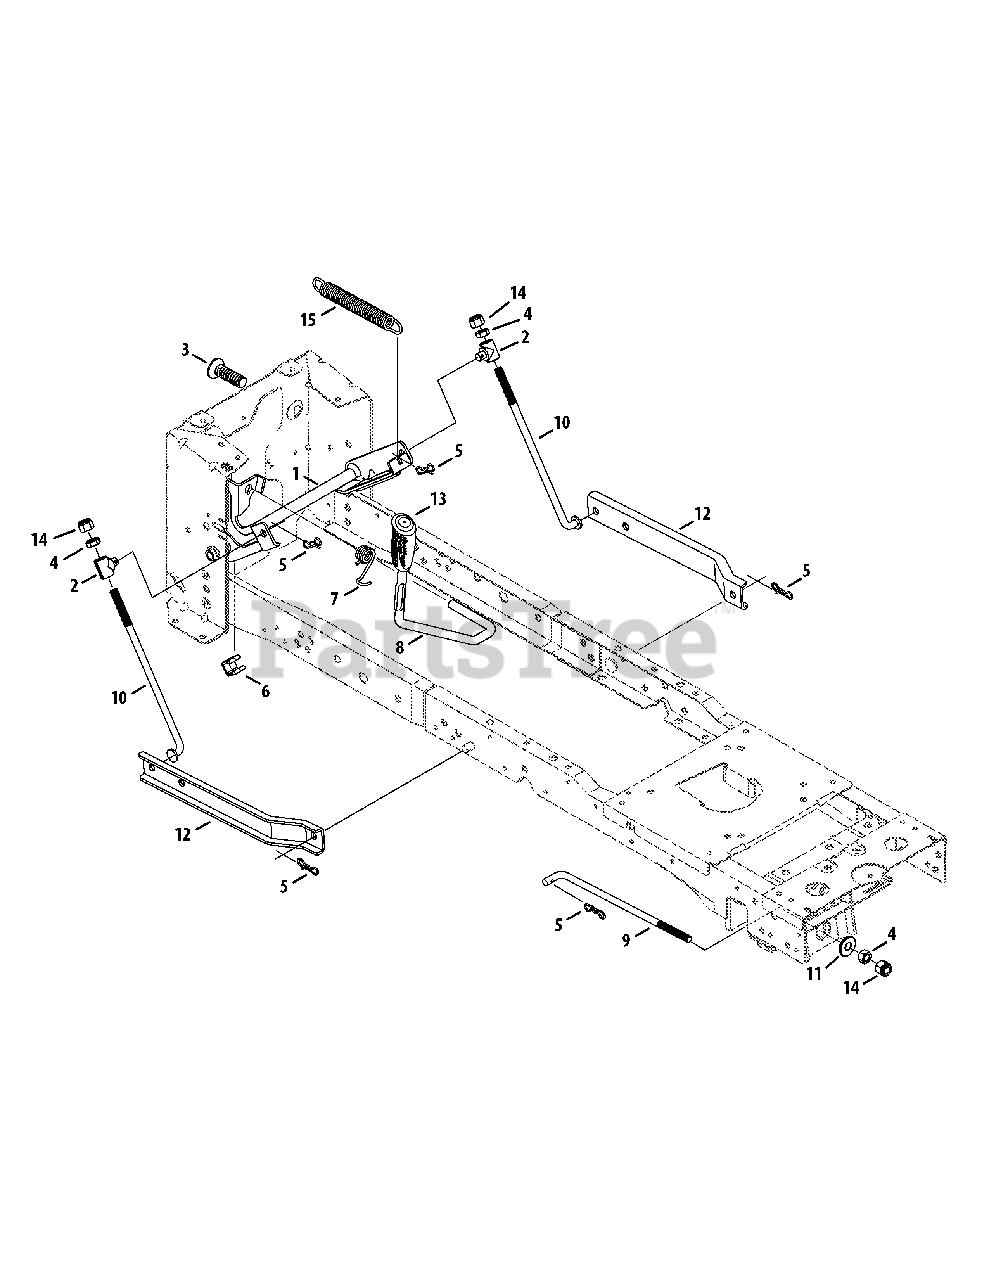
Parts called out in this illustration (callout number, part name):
1	Shaft Assembly, Lift
2	Ferrule, .510 x .496
3	Spring Insert
4	Nut, Jam, 1/2-13
5	Bow-Tie Cotter Pin
6	Spacer, .76 ID x .93 LG
7	Torsion Spring
8	Deck Lift Handle
9	Deck Lift Rod
10	Lift Adjustment Link
11	Pivot Cup
14	Hex Lock Nut, 1/2-13
15	Lift Assist Spring
